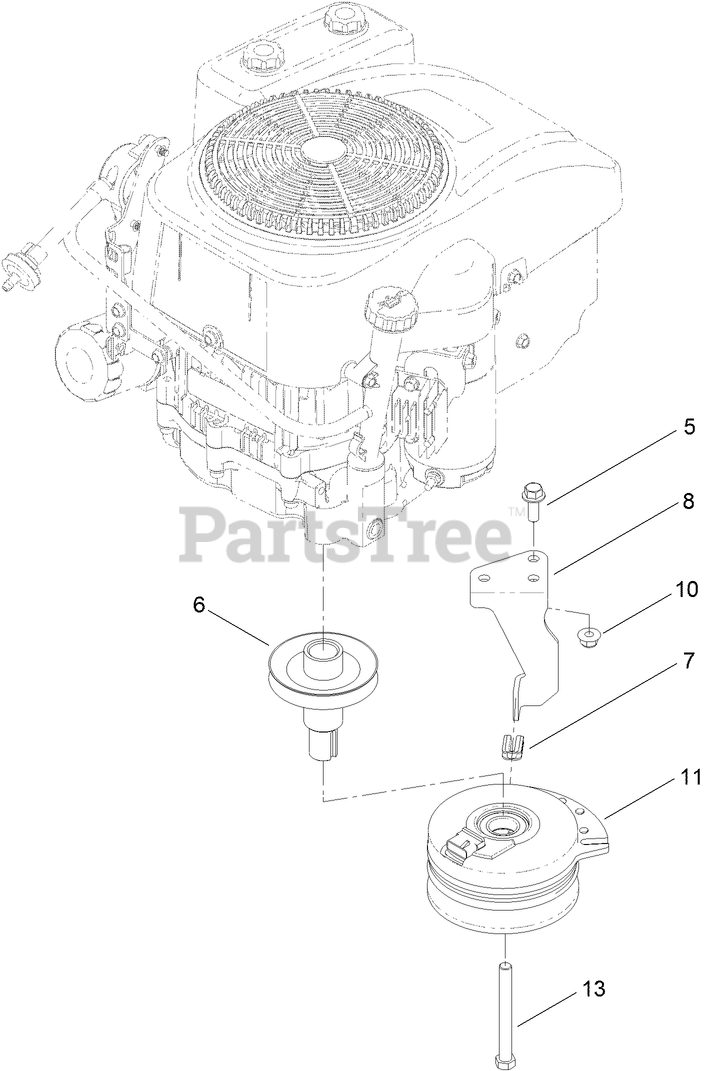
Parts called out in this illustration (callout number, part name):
5	SCREW-HHF
6	PULLEY-ENGINE
7	ISOLATOR-CLUTCH
8	STOP-CLUTCH (NARROW)
10	NUT-HF, NI
11	CLUTCH-ELECTRIC
13	SCREW-HH
